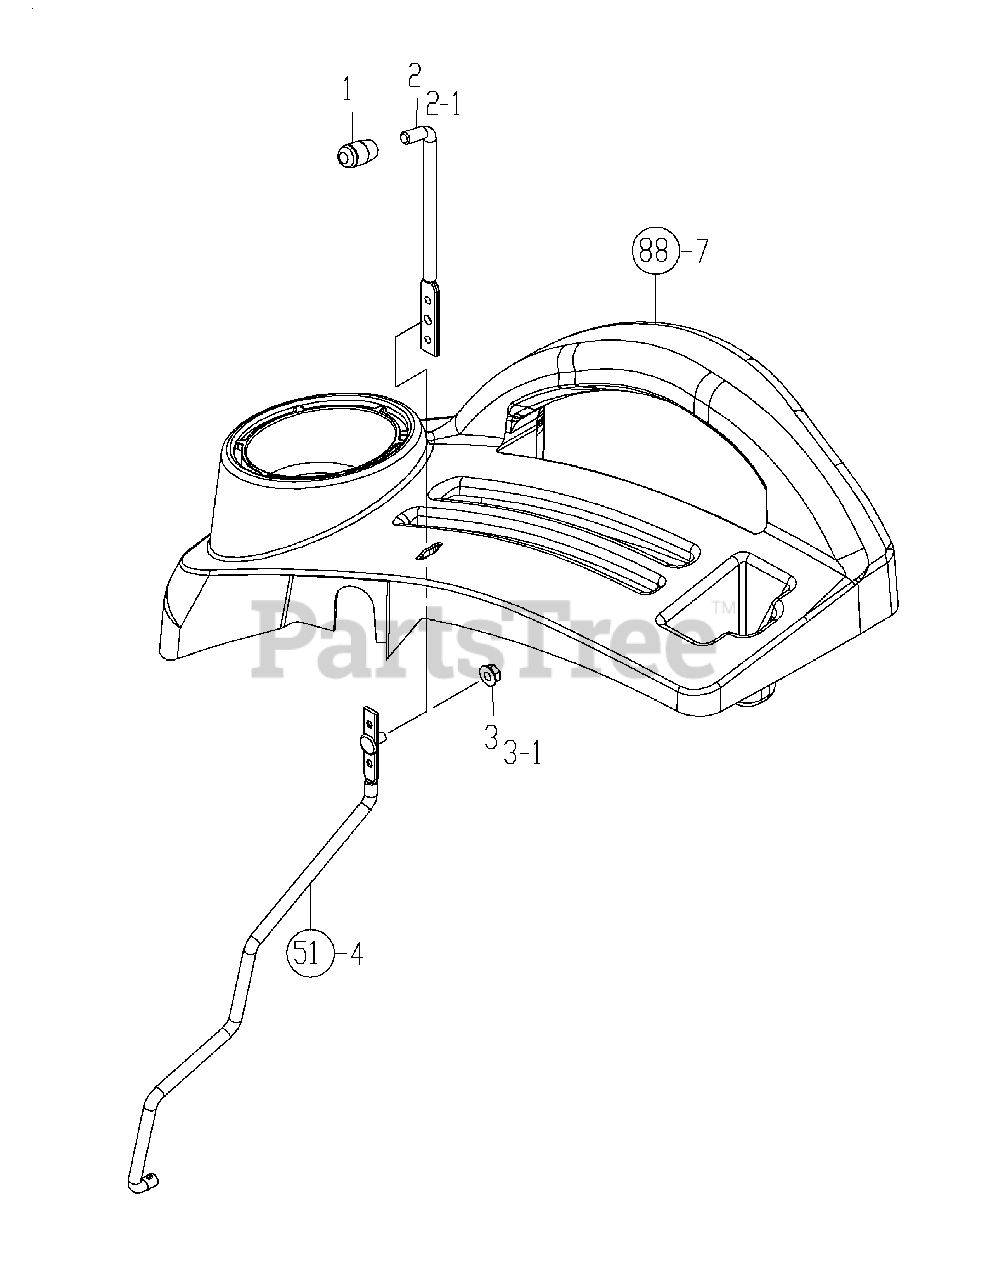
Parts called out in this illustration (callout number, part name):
2	ROD,C CRUISE
2-1	ROD,C CRUISE
3	NUT, 6
3-1	NUT W/WASHER 8
